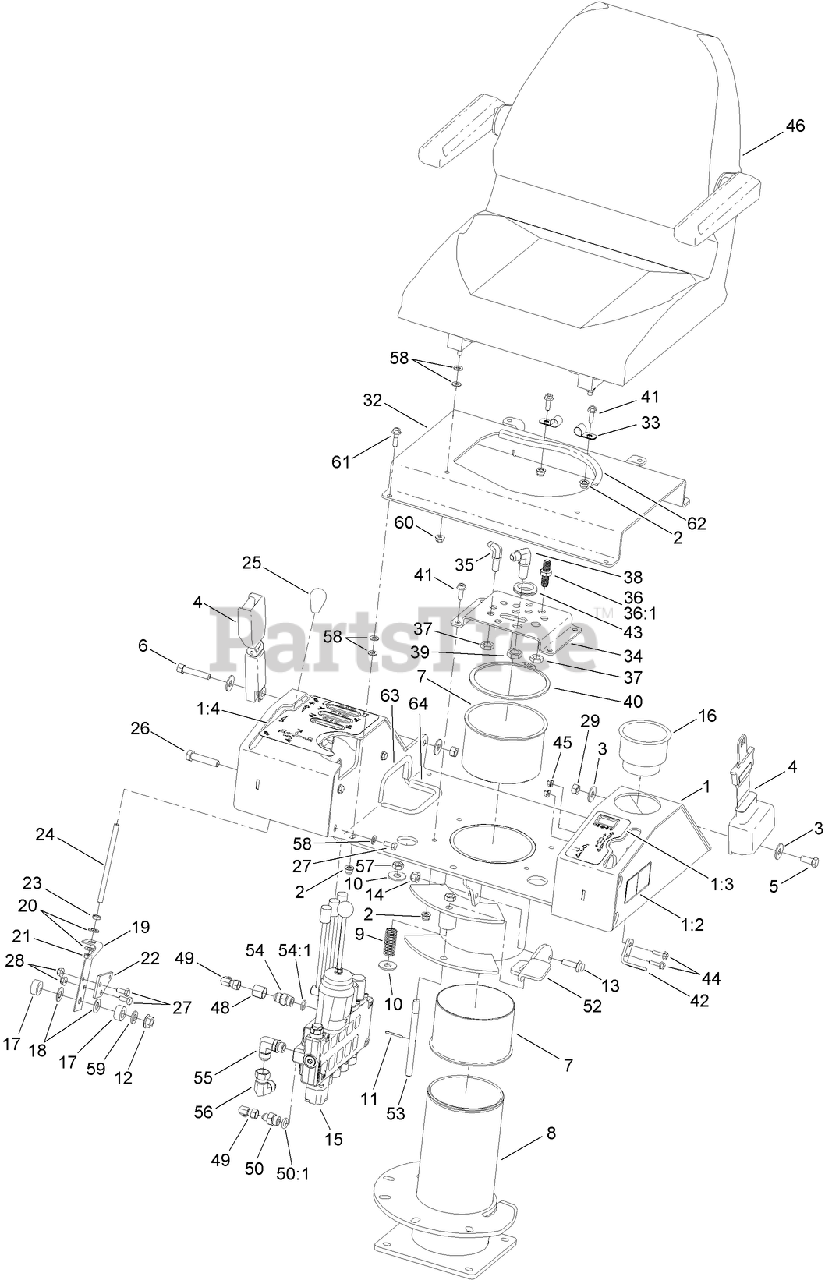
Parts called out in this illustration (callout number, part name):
1	SEAT PLATE ASM
1:2	DECAL-WARNING, NO RIDERS
1:3	DECAL-CONTROL, LH
1:4	DECAL-CONTROL, RH
2	NUT-TORQUE, PREVAILING
3	WASHER-FLAT
4	SEAT BELT ASM
5	SCREW-HH
6	BOLT-BLADE
7	PIVOT-BEARING SEAT
8	MOUNT-SEAT
9	SPRING-PIVOT LOCK, SEAT
10	WASHER-FLAT
11	PIN-COTTER
12	NUT-HF
13	SCREW-HHF
14	NUT-LOCK, NI
15	HYD CONTROL VALVE ASM
16	CUP-HOLDER
17	SPACER-GEARBOX
18	WASHER-Friction
19	LEVER-CONTROL, SPEED
20	WASHER-FLAT
21	NUT-HEX
22	PLATE-MOUNTING, CABLE
23	NUT-JAM
24	ROD-Linkage
25	KNOB-Control
26	SCREW-HH
27	SCREW-HH
28	NUT-HF, NI
29	NUT-HEX
32	MOUNT-SEAT
34	PLATE-BULKHEAD, SEAT
36	UNION-BULKHEAD
36:1	NUT-LOCK, BULKHEAD
37	NUT-LOCK, BULKHEAD
39	NUT-LOCK
40	RING-RETAINING
41	SCREW-HH
42	PLATE-MOUNT
43	GROMMET-RUBBER
44	SCREW-HHF
45	NUT-FLANGE, NI
46	SEAT ASM
48	REDUCER-TUBE
49	ELBOW-SWIVEL, 90 DEG
50	CONNECTOR
50:1	O-RING
52	BRACKET-SEAT
53	ROD-SWING, SEAT
54	FITTING-STRAIGHT
54:1	O-RING
55	ADAPTER
56	ADAPTOR
57	NUT-JAM
58	WASHER-PLAIN
59	WASHER-FLAT
60	NUT-HF, LOCK
61	SCREW-HHF
62	TRIM-BATTERY
63	TRIM-CONTROL BASE
64	TRIM-CONTROL BASE
